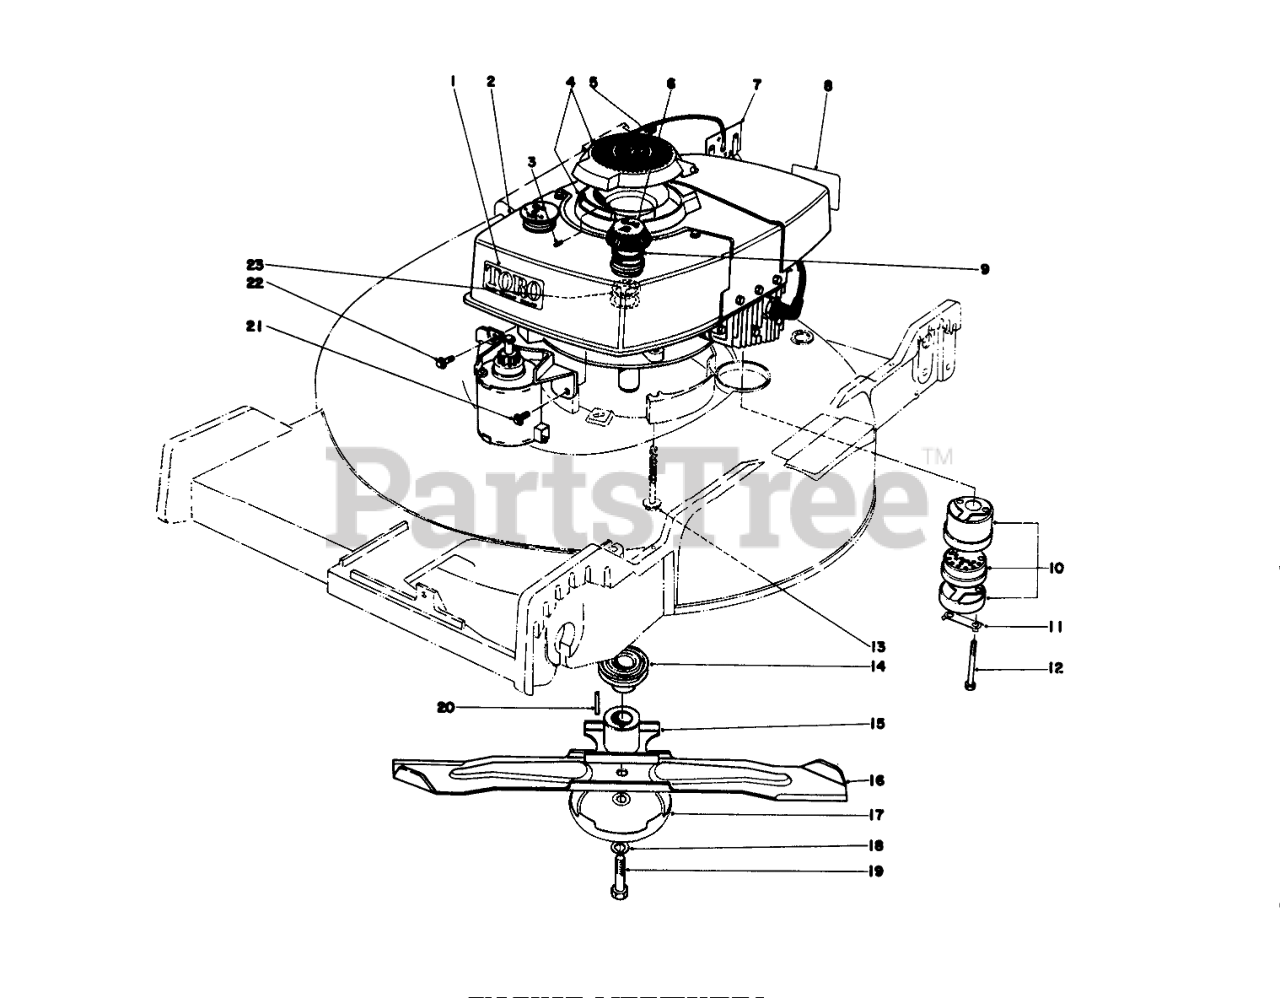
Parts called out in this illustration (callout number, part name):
1	High Torque
2	Engine
3	90 Spring Pin
4	Cover
5	WIRE CLIP
6	Gas Cap Assembly (Incl. Ref. #9 & 23)
7	SWITCH & TERM BLK CVR
8	Decal-Maintenan
9	GASKET
10	Muffler Assembly (Incl. Ref. #11 & 12)
11	CLIP - LOCKING
12	SCREW-HH
13	3/8-16 X 2-3/4 CAPSCR
14	DRIVER PULLEY
15	BLADE RETAINER WA(BLACK)
16	Blade
17	Anti Scalp Cup
18	WASHER-LOCK
19	BLADE SCREW
20	KEY-SQUARE
21	SCREW
22	Screw
23	GAS CAP BAFFLE
